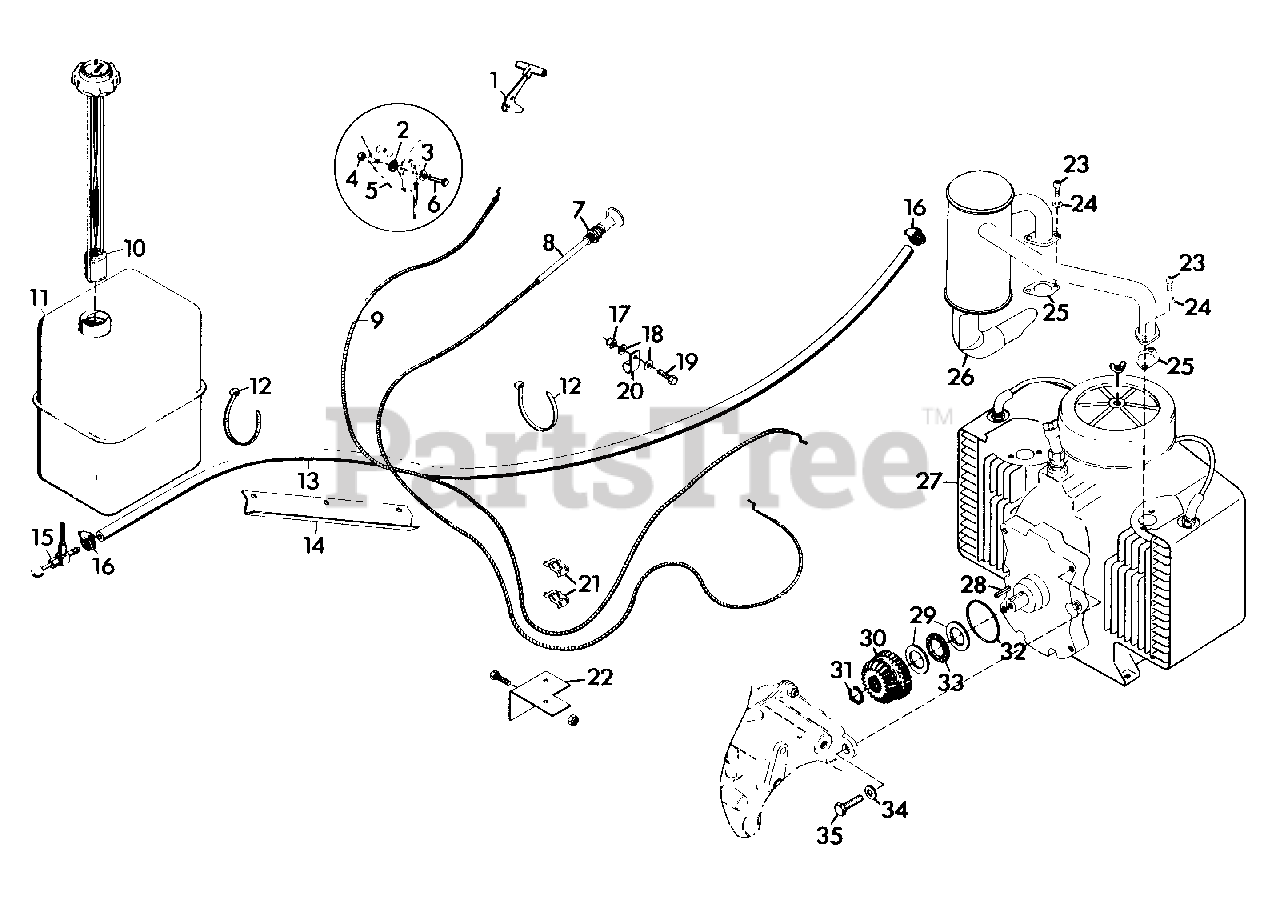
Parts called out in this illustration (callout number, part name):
1	ASSEMBLY, KNOB AND LEVER
2	WASHER, FRICTION
3	WASHER, SPRING
4	NUT, LOCK 1/4-28
5	BRACKET, MOUNTING
6	BOLT, HEX 1/4-28X.75
7	NUT, JAM 3/8-24 HEX
8	CONTROL, CHOKE
9	ASSEMBLY, CHOKE CONDUIT
10	GAUGE, GAS
11	TANK, FUEL
12	TIE, CABLE
13	LINE, FUEL
14	SHIELD, HEAT
15	VALVE, FUEL 90 DEG. REVERSE FLOW
16	CLAMP, HOSE
17	NUT, LOCK 5/16-18
18	WASHER, FLAT .344X.688X.065
19	BOLT, HEX 5/16-18X1.00
20	CLAMP, NYLON
21	CLIP, SPEED
22	BRACKET, THROTTLE AND CHOKE
23	SCREW, CAP 5/16-18X.75 S/HD
24	WASHER, LOCK 5/16-18 REG.
25	GASKET, EXHAUST
26	MUFFLER, EXAUST
27	ENGINE, 18 HP
27	ENGINE, 20 HP
28	KEY, SQUARE .250X1.250
29	RACE, BEARING THRUST 1.125X1.750X.123/.126
30	GEAR, SPUR AND BEVEL, INPUT
31	RING, RETAINING 1.125 SHAFT
32	O-RING, 3.000X3.188X.094
33	BEARING, THRUST 1.127X1.740X.078
34	WASHER, LOCK 1/2 REG.
35	BOLT, HEX 1/2-13X1.75
NS	NUT, LOCK 10-32
NS	SCREW, MACHINE 10-32X.50 PHD
